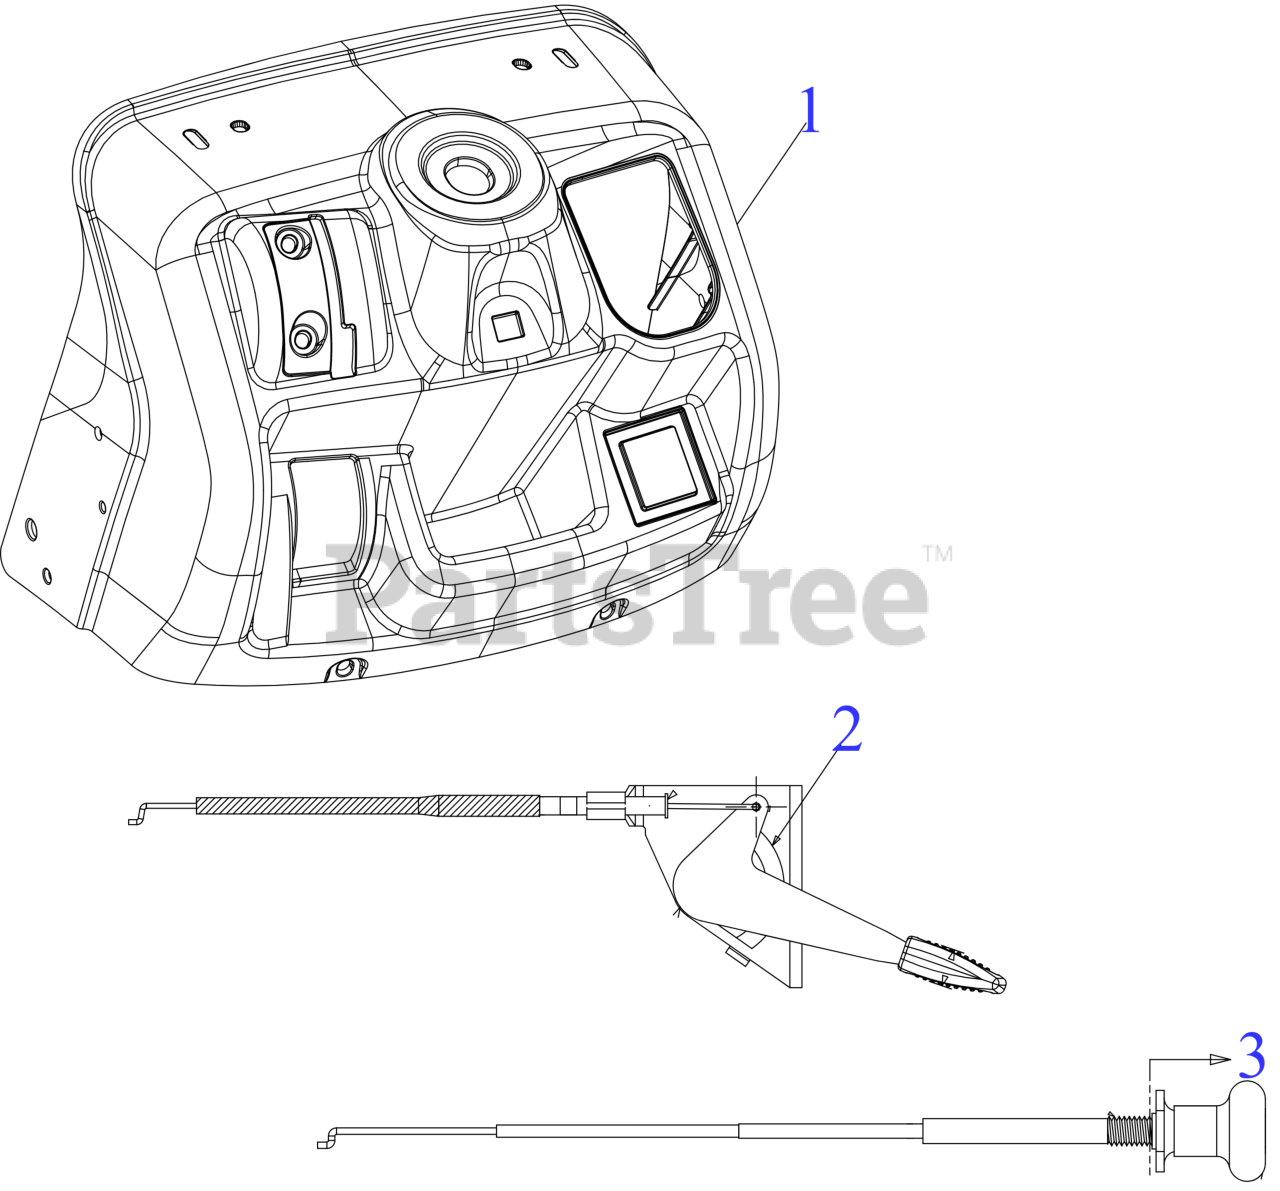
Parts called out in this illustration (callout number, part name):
1	UPPER DASH
2	THROTTLE CABLE 41.5 x .62
3	40.5" CHOKE CABLE
